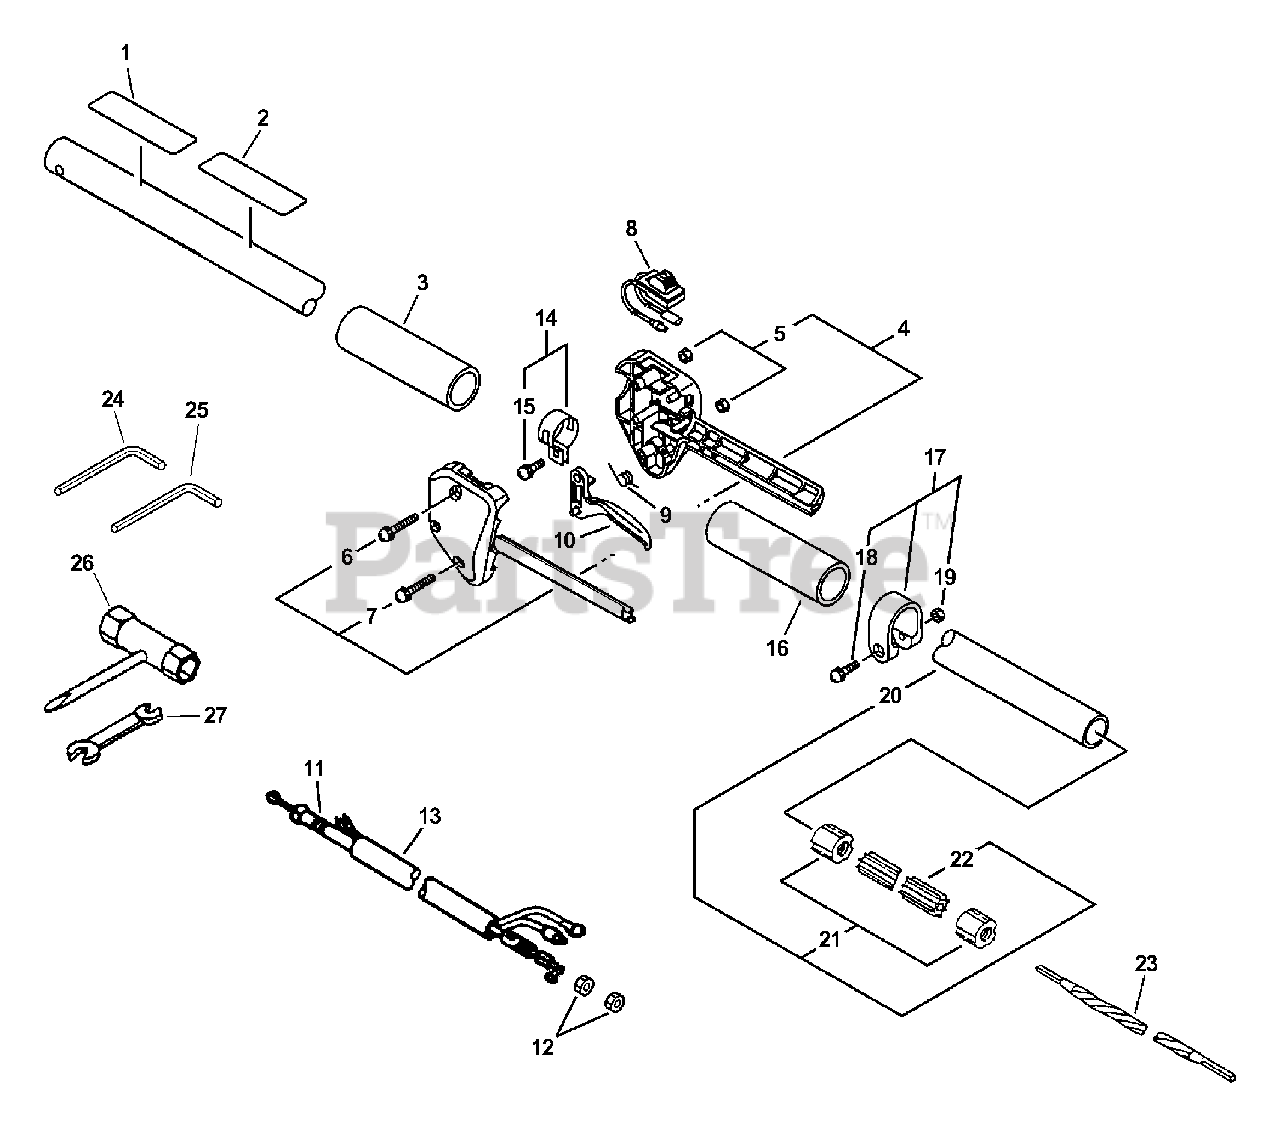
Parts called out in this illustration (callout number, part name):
1	LABEL - CAUTION -- SPANISH
2	LABEL - CAUTION
3	GRIP, HANDLE
4	CONTROL HANDLE KIT
6	SCREW - 5X35
7	SCREW - 5X25
8	IGNITION SWITCH ASSY
9	SPRING, TRIGGER
10	TRIGGER, THROTTLE
11	CABLE, THROTTLE
13	TUBE
14	CLAMP KIT
15	SCREW - 5X12
16	GRIP, HANDLE
17	CLAMP KIT
18	SCREW - 5X28
20	MAIN PIPE ASSY
22	LINER - FLEXIBLE
23	DRIVESHAFT - FLEXIBLE
24	HEX KEY - 4mm
25	HEX KEY - 3mm
26	T-WRENCH - 17X19mm
27	SPANNER - 8X10mm
